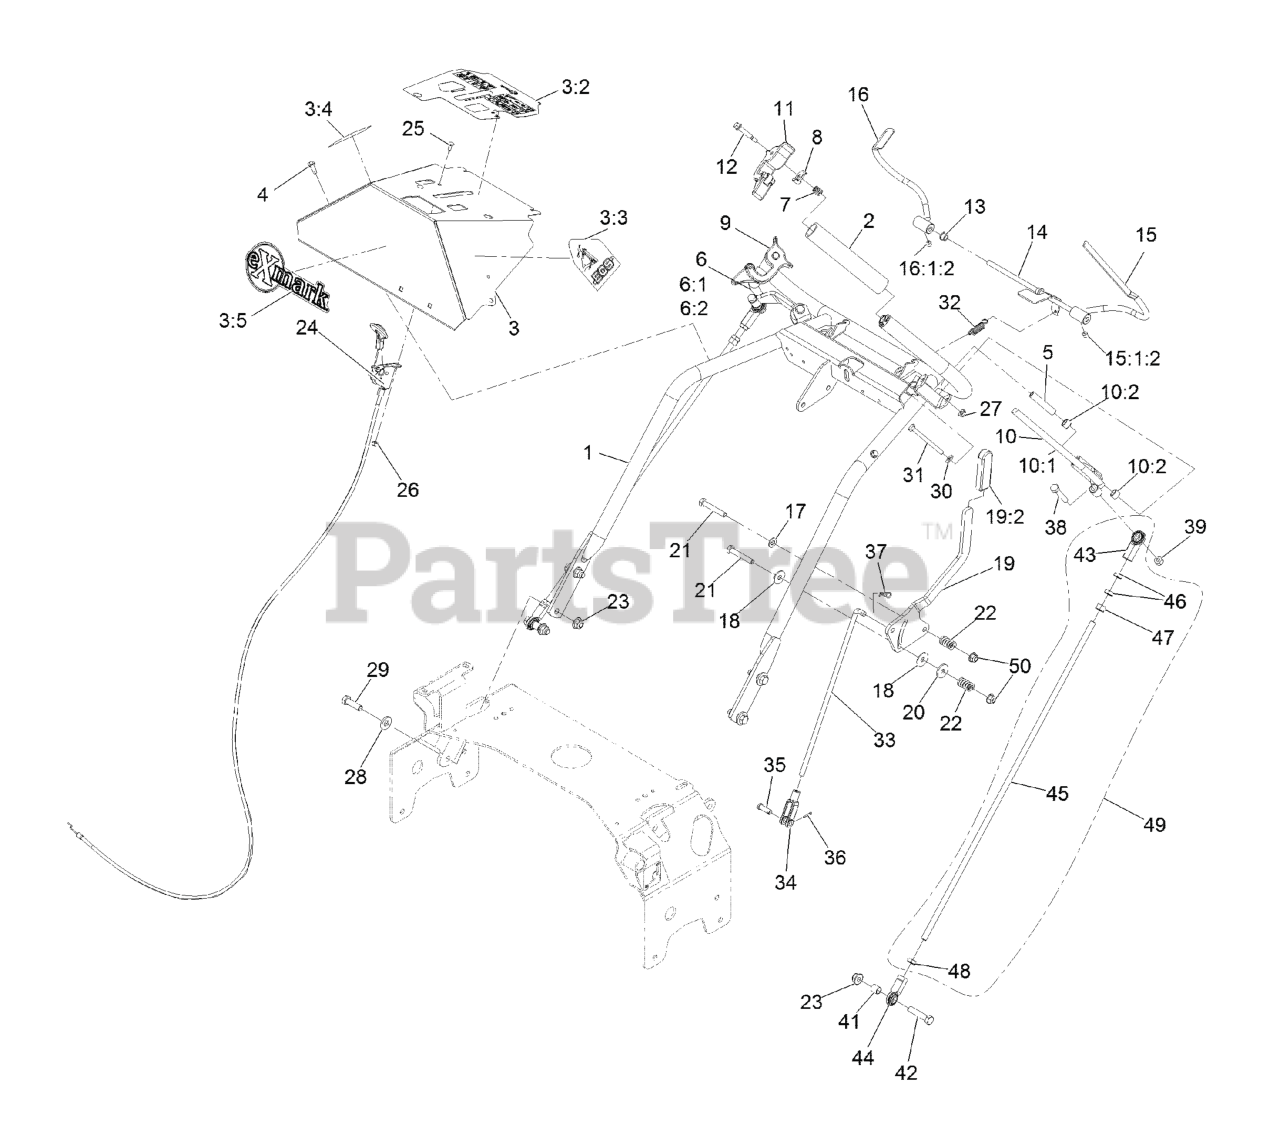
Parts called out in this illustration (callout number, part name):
1	WELD, HANDLE
2	GRIP-BAR, HANDLE
3	ASM, CONSOLE W/ DECALS
3:2	DECAL-CONSOLE
3:3	DECAL,LH ECS INSTRUCTION
3:4	DECAL,RH ECS INSTRUCTION
3:5	DECAL, EXMARK LOGO
4	SCREW-HWH
5	BUSHING-LEVER, DRIVE
6	DRIVE LEVER-ASM, RH
6:1	WLD,RH DRIVE LEVER
6:2	BUSHING, SLEEVE
7	SPRING-TANK, FUEL
8	LATCH, ECS
9	ASM,LATCH RH THUMB
10	DRIVE LEVER-ASM, LH
10:1	WLD,LH DRIVE LEVER
10:2	BUSHING, SLEEVE
11	ASM,LATCH LH THUMB
12	SCREW-SHOULDER
13	BUSHING-NYLON
14	WLD,OPC LEVER AXLE
15	WLD,LH OPC LEVER
15:1:2	SCREW-SET
16	WLD,RH OPC LEVER
16:1:2	SCREW-SET
17	WASHER-PLAIN
18	WASHER-FRICTION
19	LEVER, SHIFT W/GRIP
19:2	GRIP-HANDLE, STEERING
20	WASHER-FRICTION
21	SCREW-HH
22	SPRING-COMPRESSION
23	NUT-HF, NI
24	CONTROL-THROTTLE
25	BOLT-CARR
26	NUT-LOCK, NI
28	WASHER-BELLEVILLE
29	SCREW-HH
30	WASHER-FLAT
31	SCREW-HH
32	SPRING-EXTENSION
33	ROD,SPEED CONTROL
34	YOKE-ADJUSTABLE
35	PIN-CLEVIS
36	PIN-COTTER
37	PIN-COTTER
38	SCREW-HH
39	NUT-LOCK, NI
41	SPACER-TUBE, PUMP LINK
42	SCREW-HH
43	JOINT-BALL, END
44	JOINT-BALL END, LH
45	LINK,DRIVE (PLTD)
46	NUT-HJ
47	NUT-HEX
48	NUT-HEX JAM, LH
49	DRIVE LINK ASM
50	NUT-HF, NI
